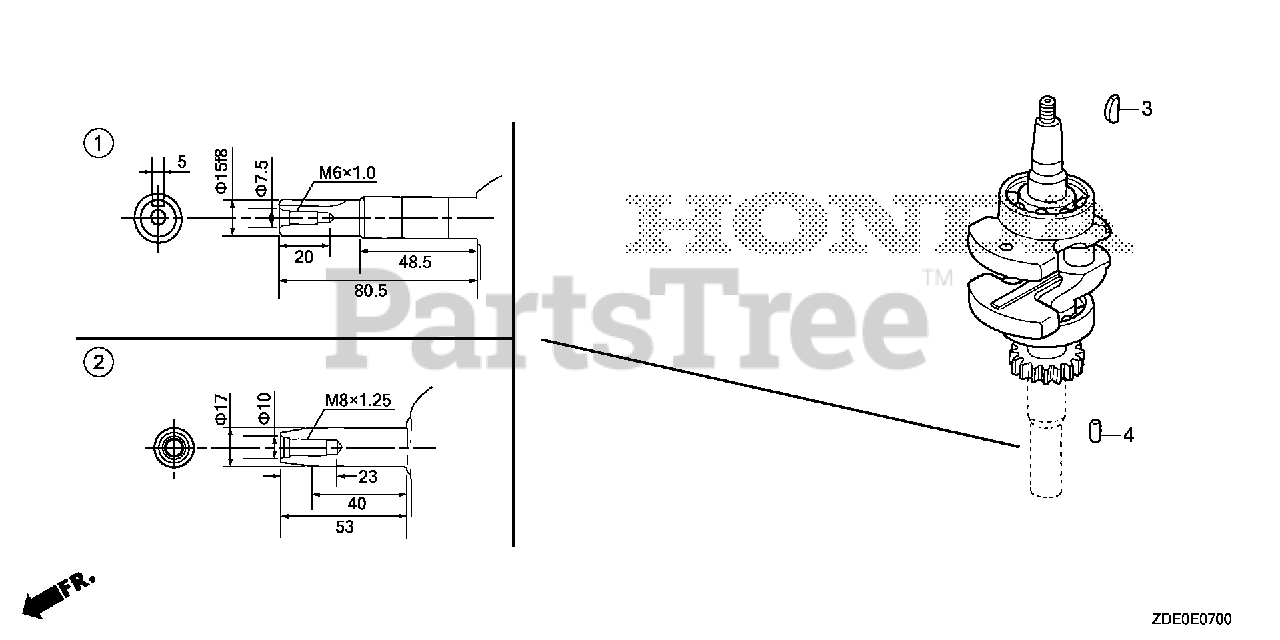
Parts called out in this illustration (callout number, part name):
1	CRANKSHAFT
3	KEY, SPECIAL
4	KEY (5MM)
